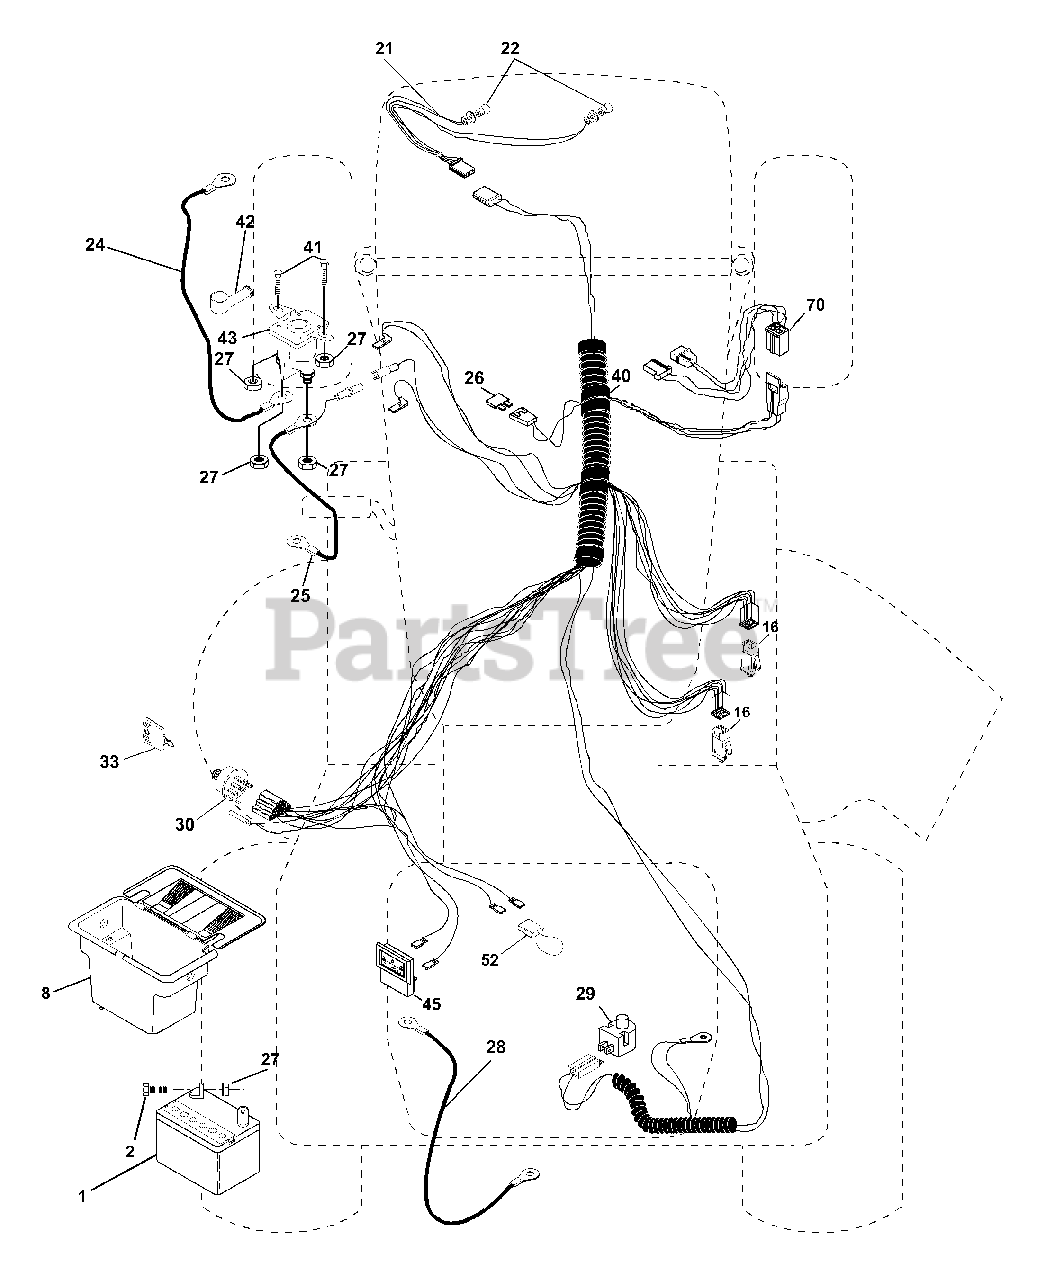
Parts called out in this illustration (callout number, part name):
1	Battery 12 Volt 25 Amp
2	Bolt Hex Hd 1/4-20unc X 3/4
8	Case Battery Mech Hinge
16	Switch Interlock Push-In
21	Harness Socket Light
22	Bulb, Light # 1156
24	Cable Battery
25	Cable Battery 6 Ga Red w/16 wire
26	Fuse 15 Amp
27	Nut Keps Hex 1/4-20 Unc
28	Cable Ground 6ga 12 black
29	Switch Plunger Nc Gray
30	Switch Ign
33	Key Ign
40	Harness Ign
41	Bolt Fin Hex 1/4-20uncx 1/2
42	Cover Terminal Red
43	Solenoid
45	Ammeter Rectangular
52	Protection Loop
70	Harness Engine
